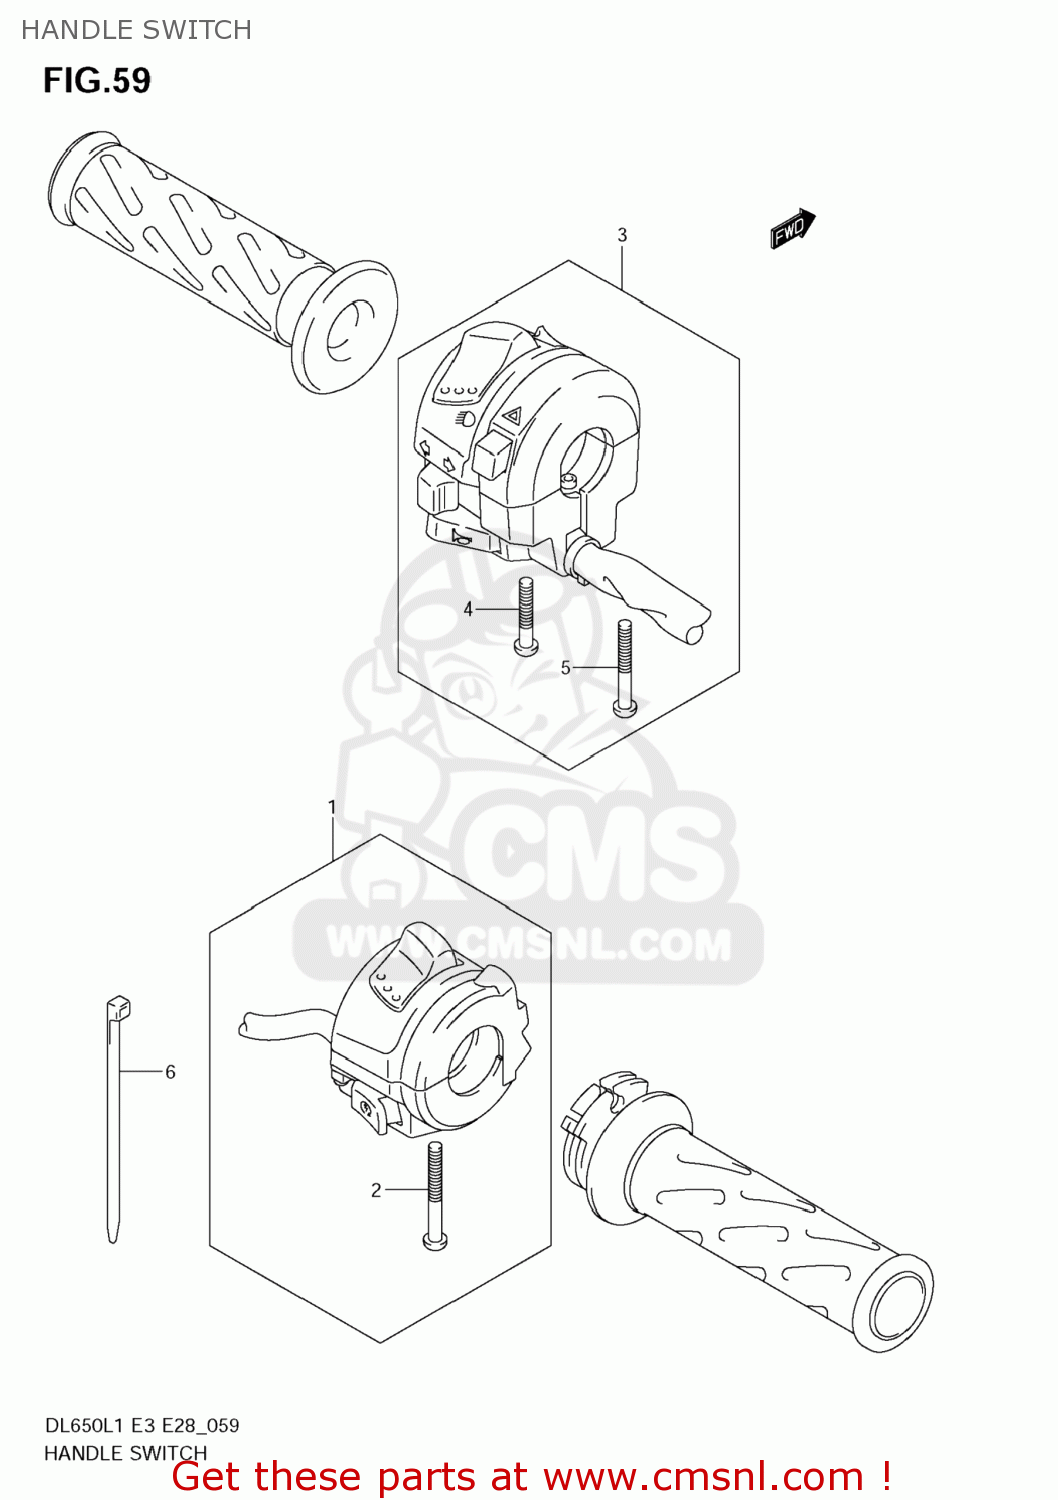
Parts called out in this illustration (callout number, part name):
1	SWITCH ASSY,HANDLE,R
2	SCREW
3	SWITCH ASSY,HANDLE,L
4	SCREW
5	SCREW
6	CLAMP(L:145)
